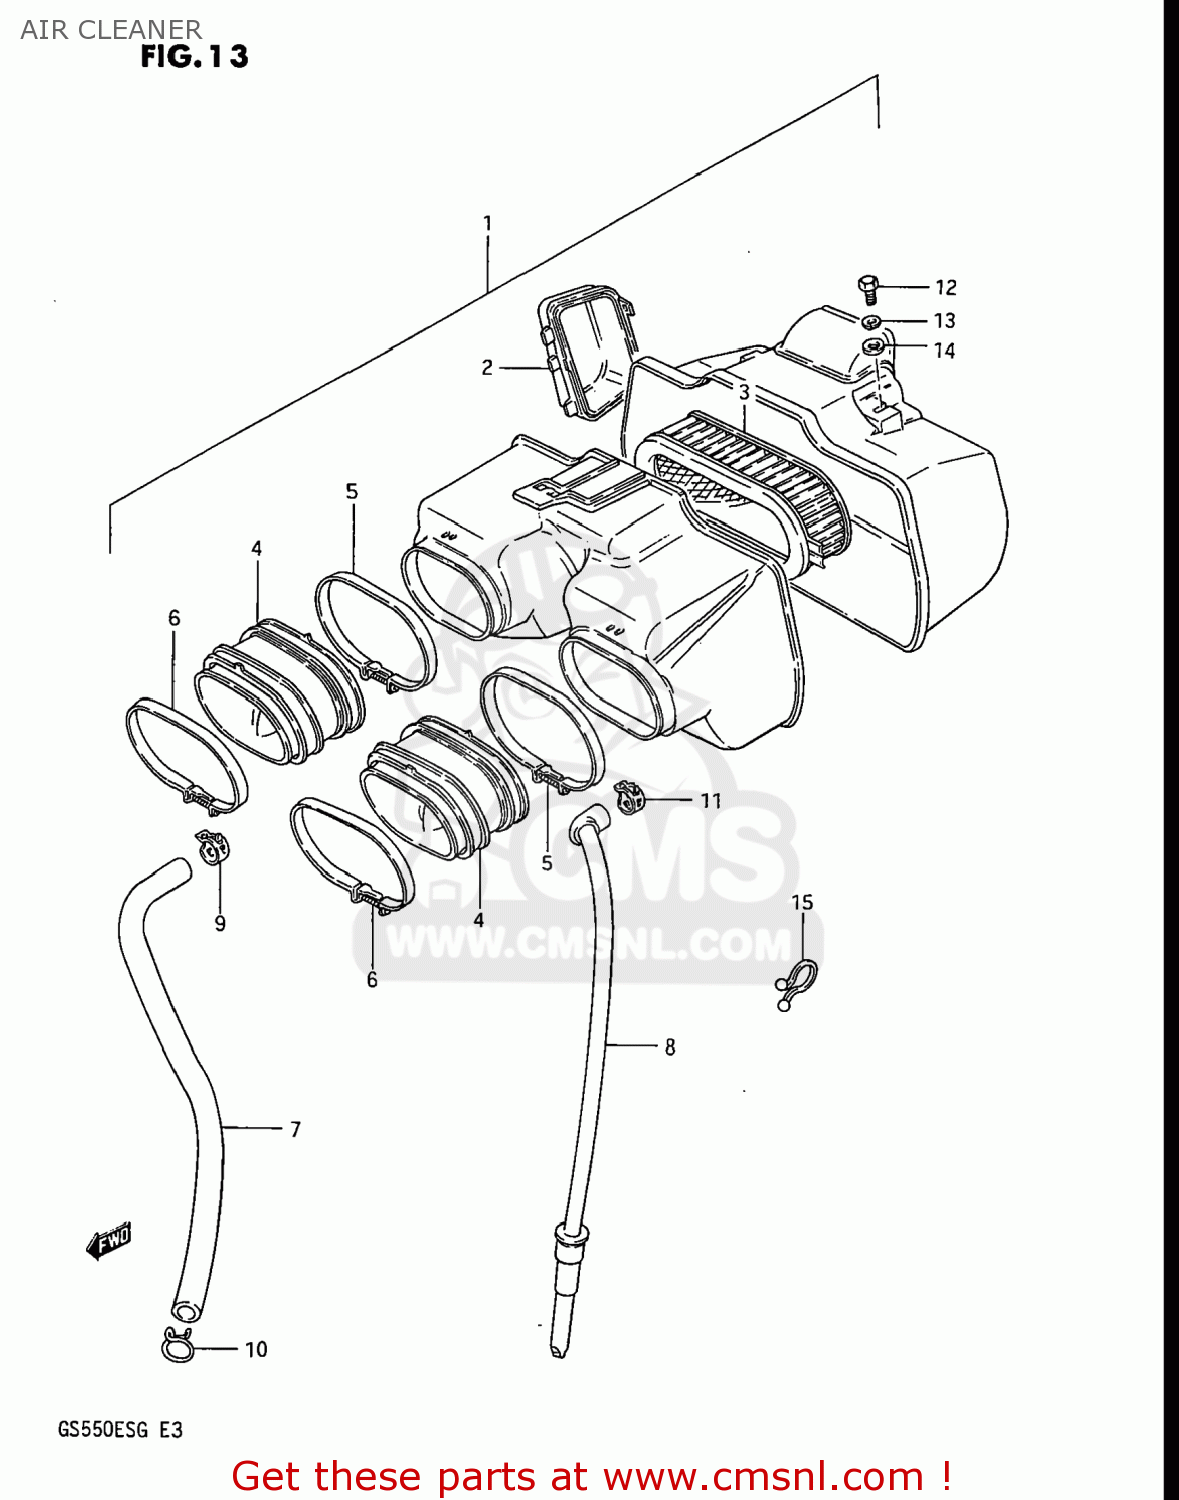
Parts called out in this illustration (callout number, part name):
1	CLEANER ASSEMBLY,AIR
2	CAP,AIR CLEANER
3	FILTER,AIR CLEANER
4	TUBE,AIR CLEANER OUTLET
5	CLAMP,AIR CLEANER
6	CLAMP,CARBURETOR SIDE
7	TUBE,BREATHER
8	DRAIN TUBE
9	CLIP
10	CLIP,BREATHER TUBE
11	CLIP
12	BOLT, UPPER
13	LOCK WASHER
14	WASHER
15	CLIP(ID:16)
